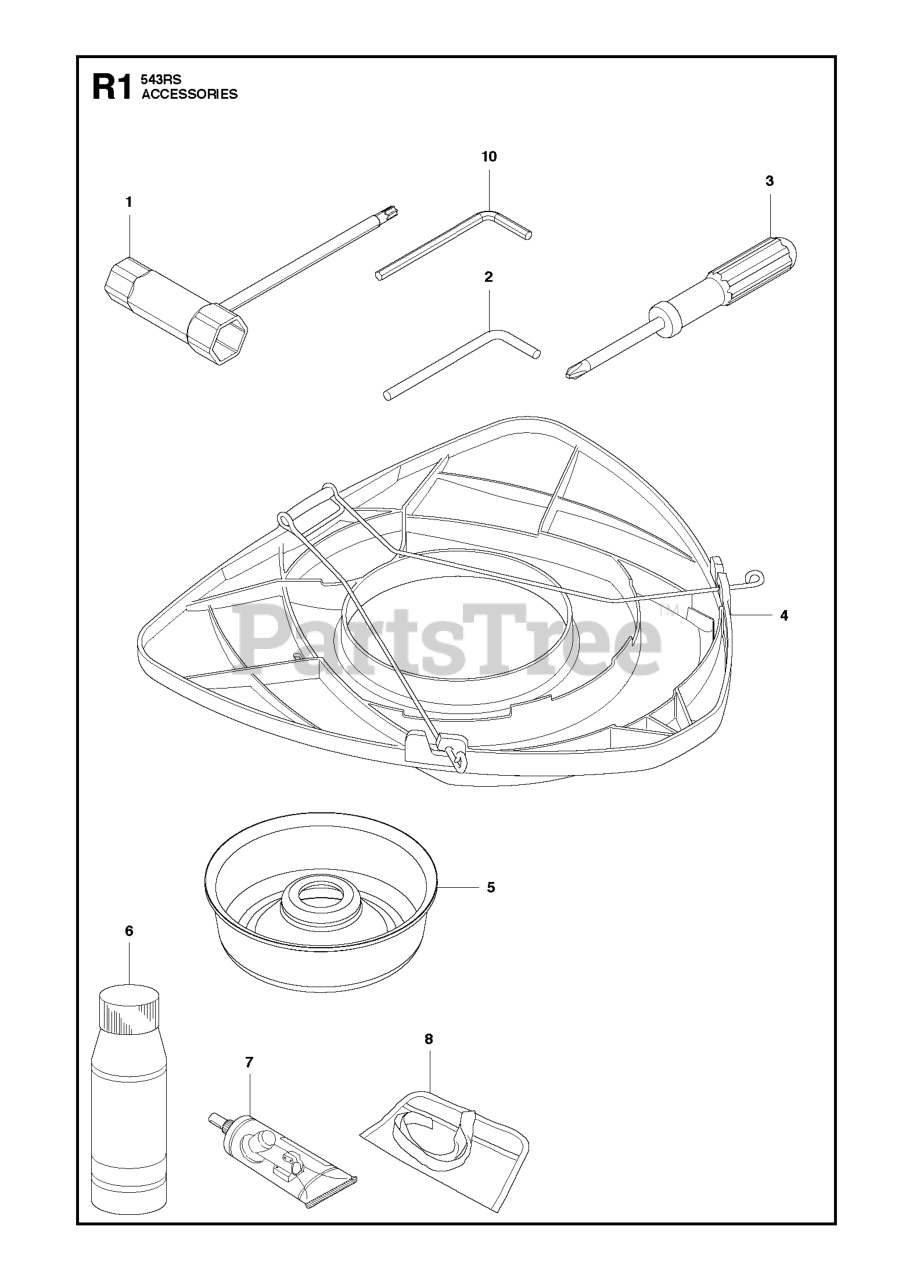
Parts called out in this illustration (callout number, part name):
4	TRANSPORT GUARD
5	SUPPORT CUP
6	Air Filter Oil 1l.
7	BEVEL GEAR GREASE
10	WRENCH
